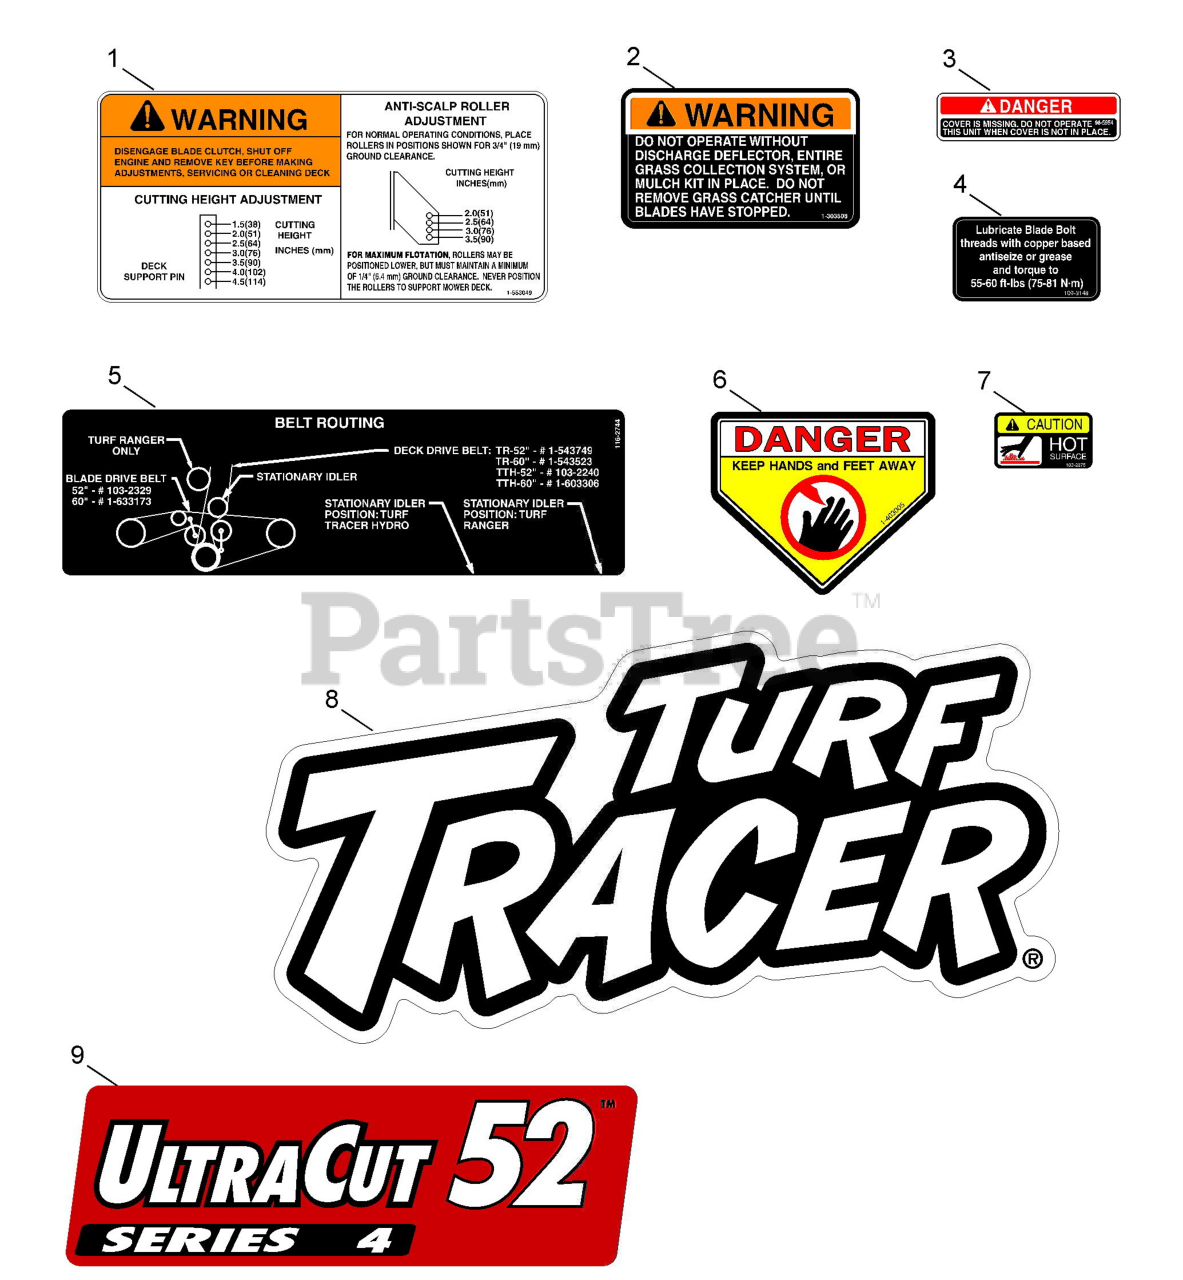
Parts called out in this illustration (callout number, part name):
1	DECAL,ANTI SCALP
2	DECAL-WARNING, DISCHARGE
3	DECAL-COVER, MISSING
4	DECAL,BOLT TORQUE
5	DECAL-BELT ROUTING
6	DECAL-DANGER
7	DECAL-CAUTION
8	DECAL,TTH MODEL
9	DECAL,ULTRACUT 52 SERIES
